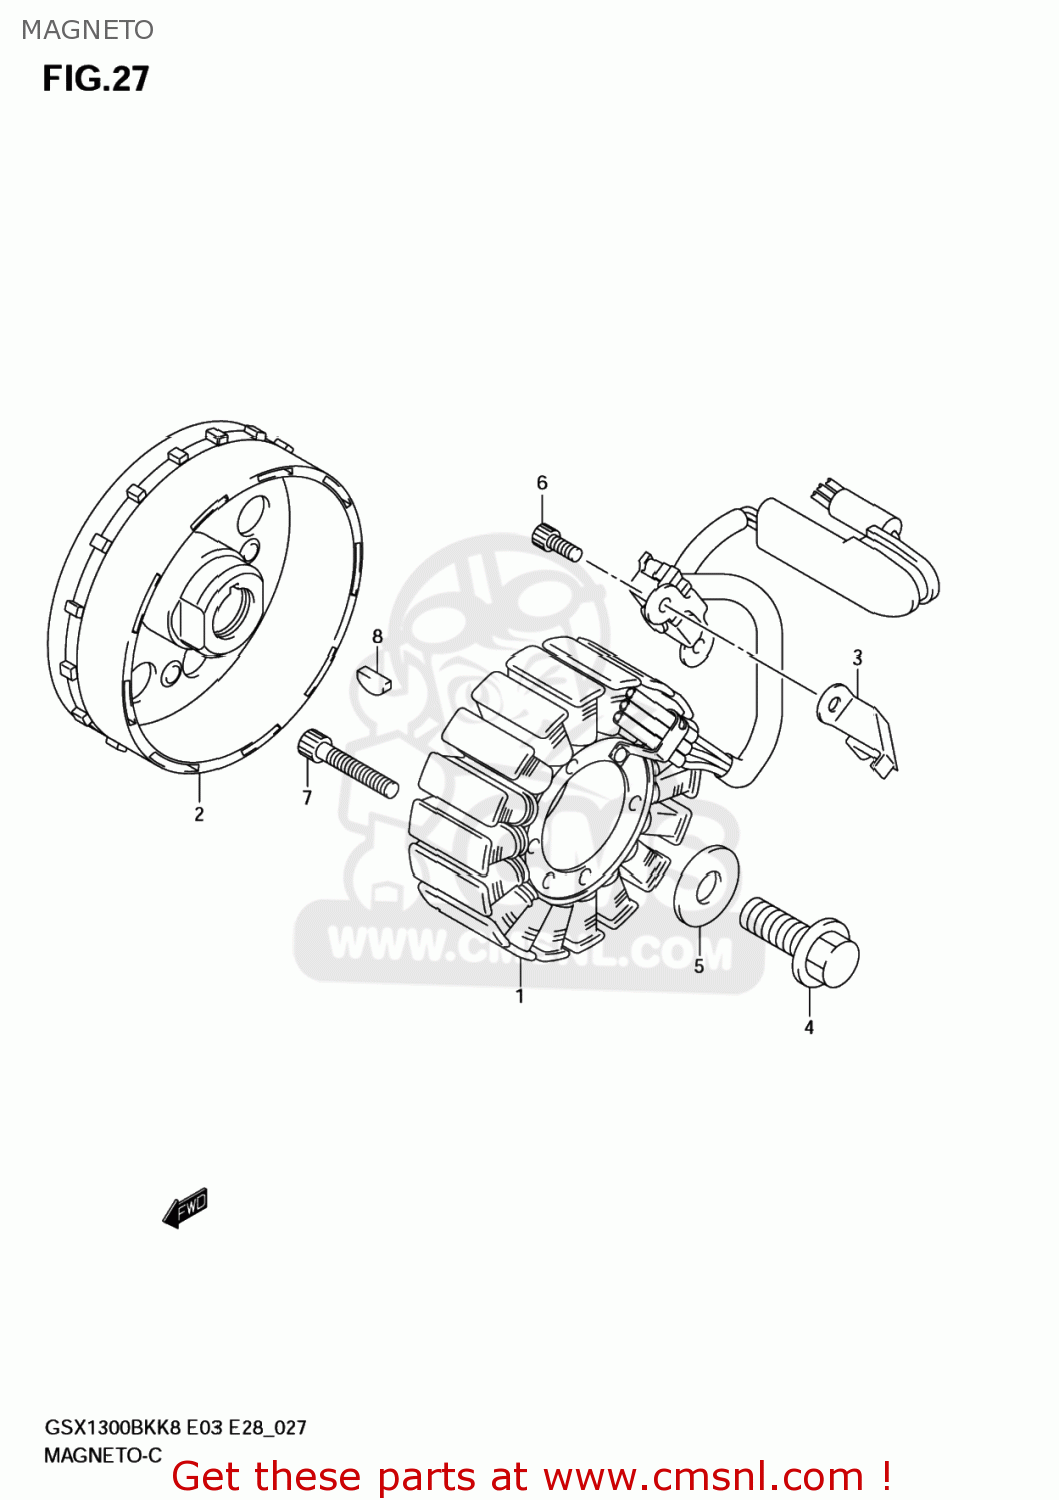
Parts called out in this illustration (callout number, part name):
1	STARTER ASSY
2	ROTOR ASSY
3	CLAMP,MAGNETO LEAD
4	BOLT(12X30)
5	WASHER(12X30X3)
6	BOLT
7	BOLT
8	KEY
